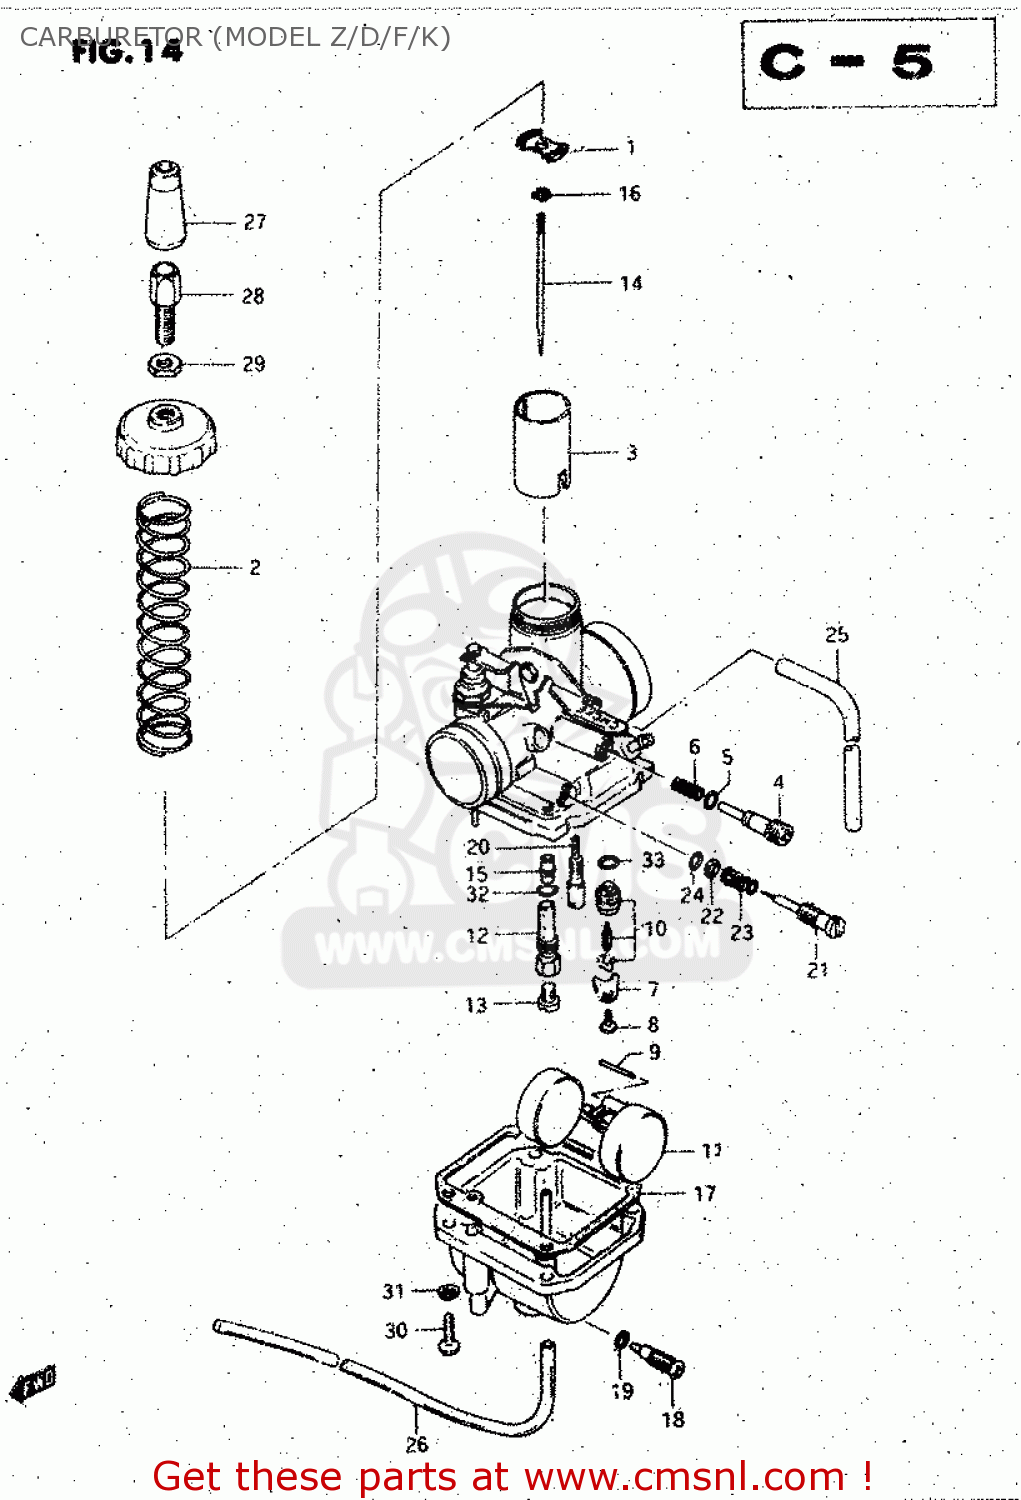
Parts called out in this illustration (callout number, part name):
1	STOPPER,NEEDLE CLIP
2	SPRING
3	VALVE,THROTTLE
4	SCREW,THROTTLE STOP
5	O RING
6	SPRING
7	PLATE,NEEDLE VALVE FITING
8	SCREW
9	PIN,FLOAT
10	VALVE ASSY,NEEDLE
11	FLOAT
12	HOLDER ASSY,JET
13	JET,MAIN(95)
14	NEEDLE, JET
15	JET,NEEDLE(0-4)
16	CLIP
17	GASKET (NAS)
18	PLUG,DRAIN
19	O RING
20	JET,PILOT(20)
21	SCREW,PILOT AIR
22	WASHER
23	SPRING
24	O RING,PILOT AIR SCREW
25	HOSE
26	HOSE
27	CAP,RUBBER
28	ADJUSTER,CABLE
29	NUT
30	SCREW
31	LOCK WASHER
32	O RING
33	O RING
